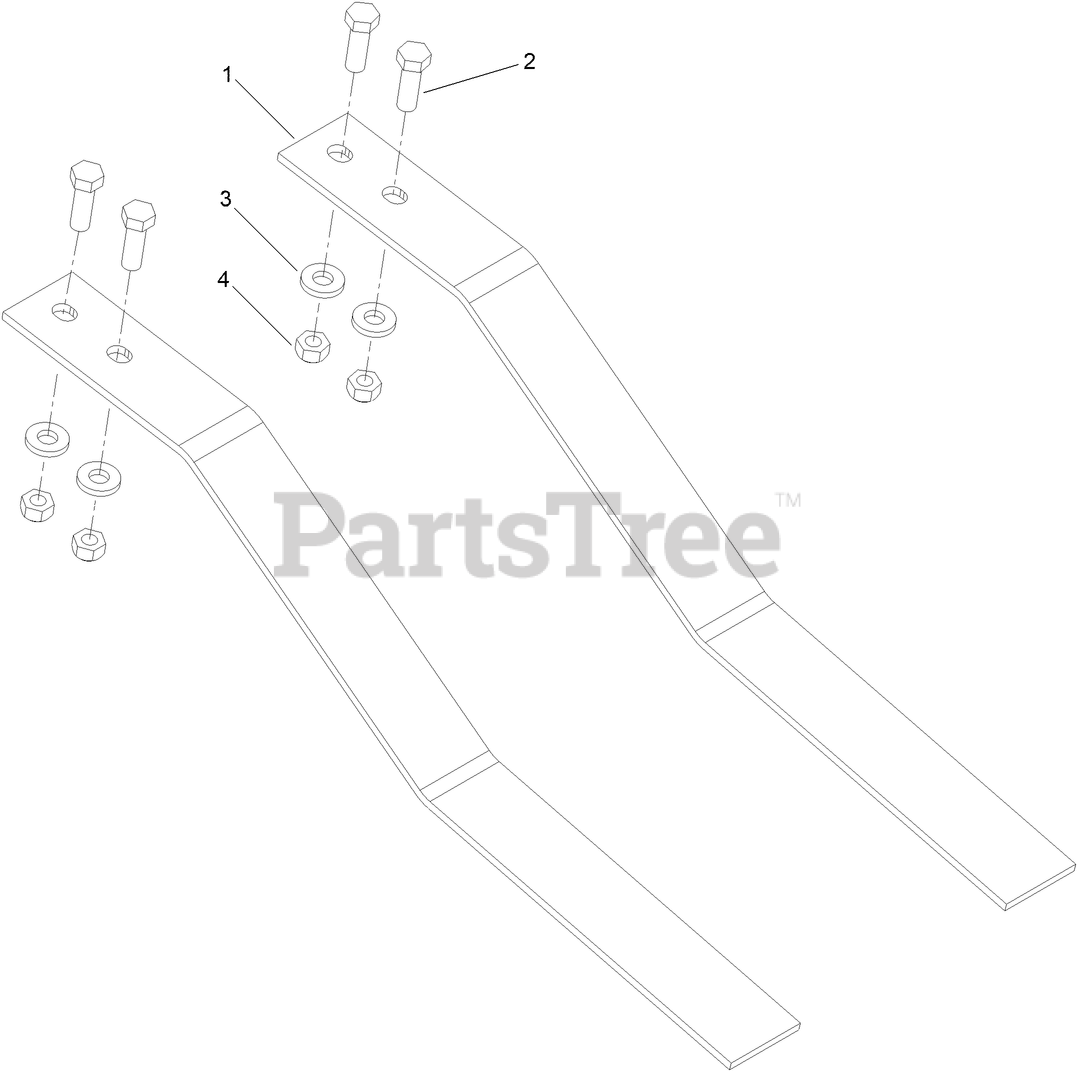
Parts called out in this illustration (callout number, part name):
1	SPRING-SHOE
2	SCREW-HH
3	WASHER-HARDENED
4	LOCKNUT
